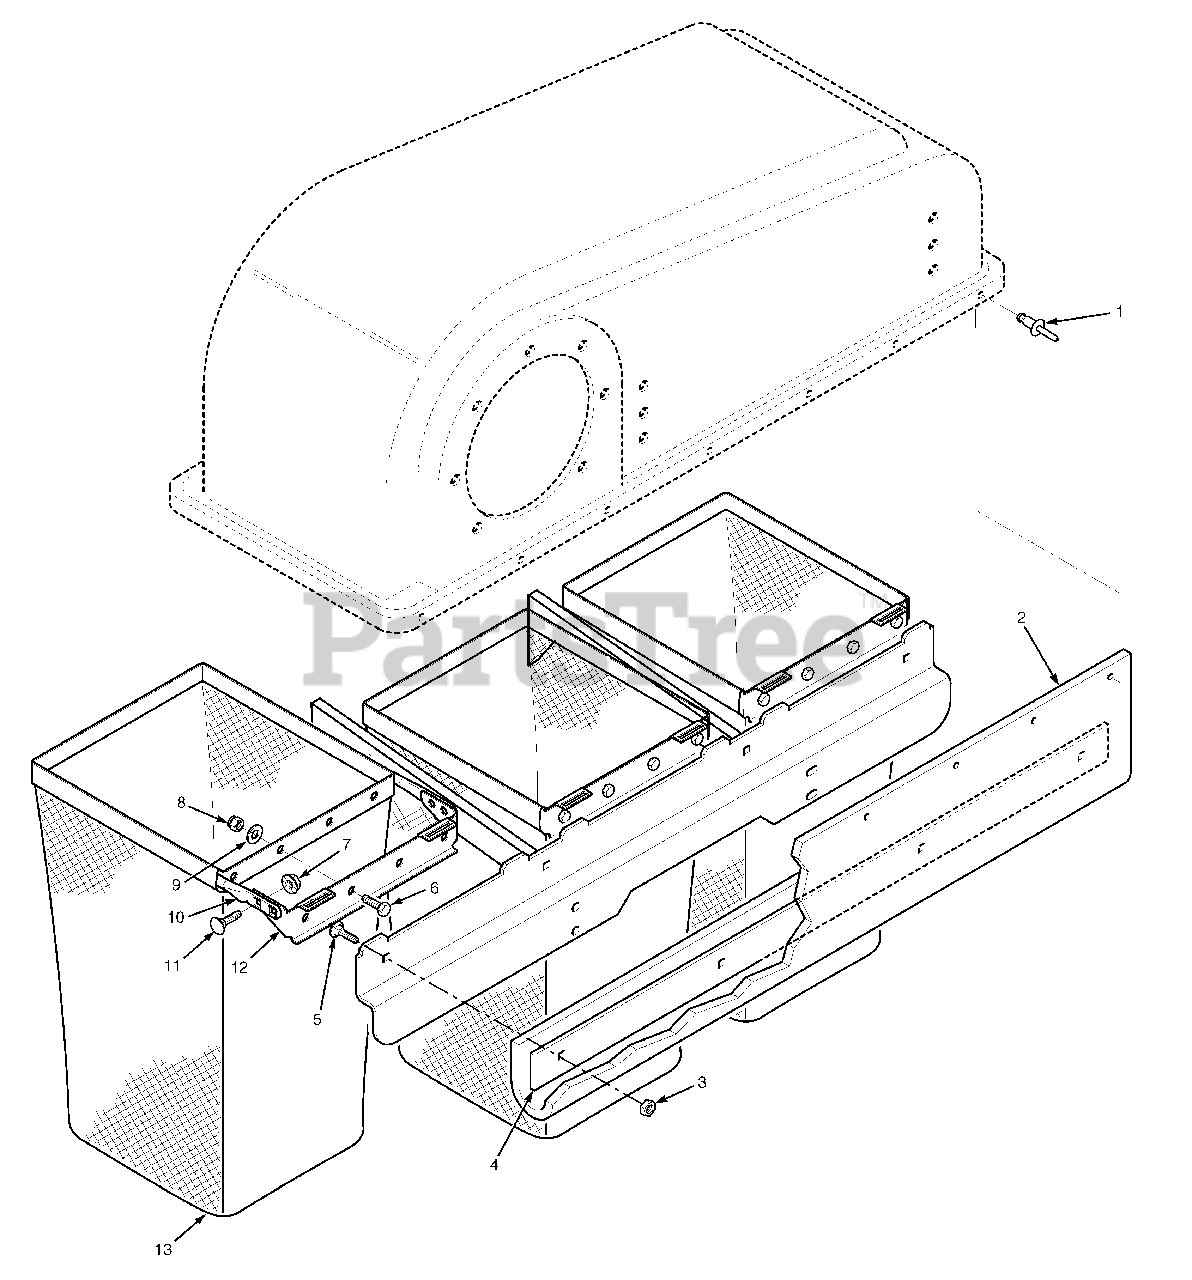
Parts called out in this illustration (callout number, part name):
1	Pop Rivet, 3/16 x .652
2	Seal, Hood
3	Lock Nut, 1/4-20 Center Lock
4	Retainer, Seal
5	Bolt, Carr. 1/4-20 x 3/4"
6	Bolt, Hex Head 5/16-18 x 3/4"
7	Nut, Serrated Flange 5/16-18
8	Nut, Elastic Stop 5/16-18
9	Flatwasher, 5/16-.375 x .875 x .083
10	Tube, Bag Support
11	Bolt, Carr. 5/16-18 x 3/4"
12	Mount, Bag Frame Tube
13	Bag Assembly, GC-STT
